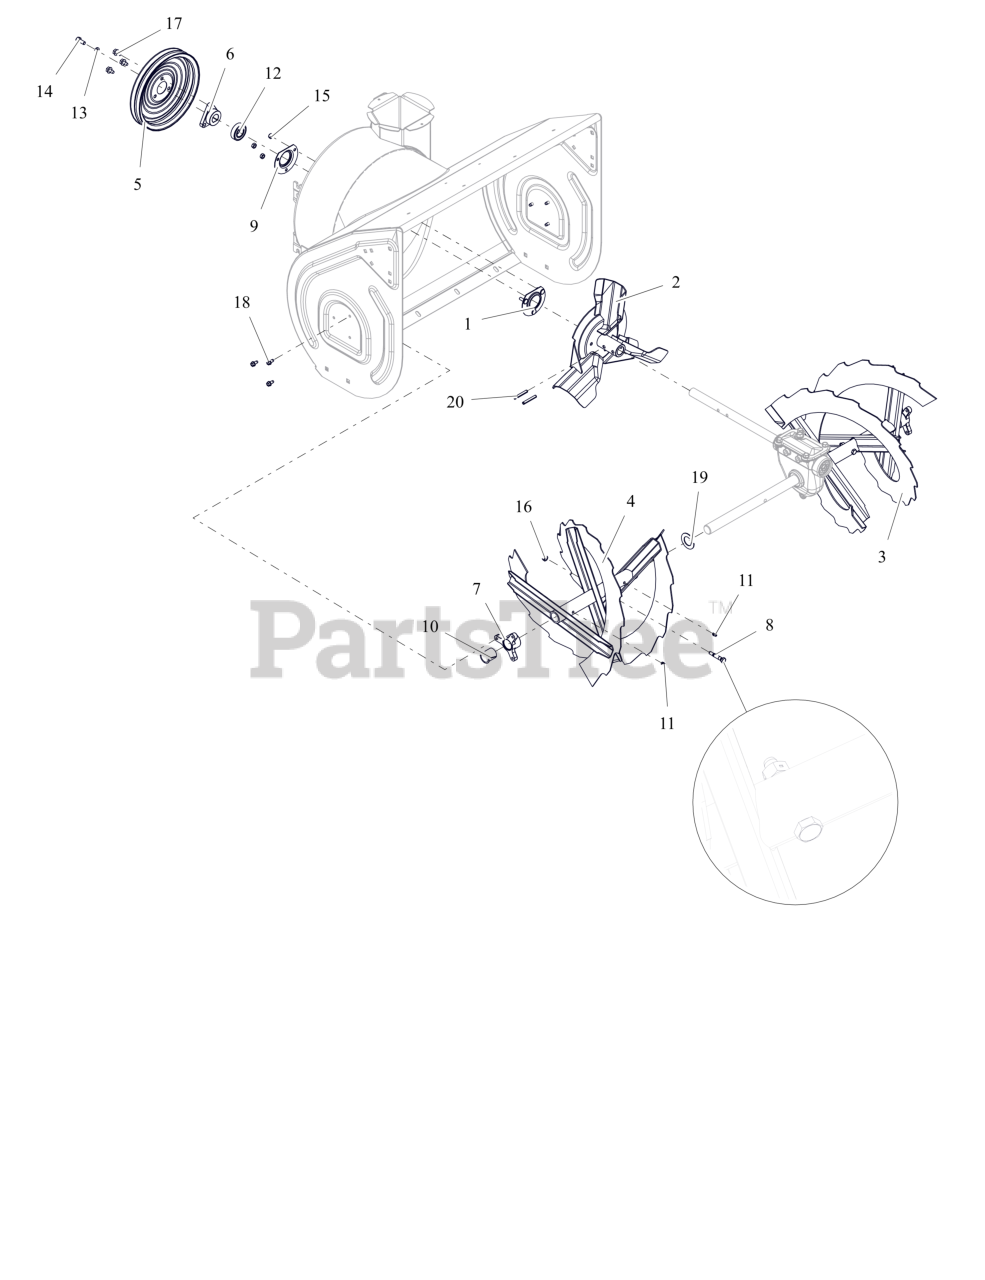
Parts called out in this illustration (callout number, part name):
1	BEARING FLANGE
2	IMPELLER, 3 BLADE-14"
3	RAKE, LH-28"(1 ID X 15.75 OD)
4	RAKE, RH-28"(1 ID X 15.75 OD)
5	PULLEY, SPIN FORM DUAL GROOVE
6	PULLEY HUB, D-BORE .87 PRO
7	BUSHING, RAKE SHAFT 1"
8	SHEAR BOLT SERVICE ASSEMBLY (INCLUDES NUT)
9	BEARING FLANGE
10	BSHG-FLG SPLIT NYLINER 1.0" HP
11	ZERK,FITTING .25X.125 DRIVE IN
12	BRG-BALL .876X1.75X.50 RSTFP
13	WSHR, LK-HVY .312X.097 ZCC
14	BLT, HEX .31-24X.750 G5 ZCC
15	NUT,LK-CTR .25-20 GA ZCC
16	NUT,LK-CTR .31-18 GA ZCC
17	SCR,TAP .312-18X.50 HWH TR ZCC
18	SCR-TAP .25-20X.50 HWH ZCC
19	WSHR- FLT 1.010X1.755X.062 ZCC
20	PIN-ROLL .250X1.75
